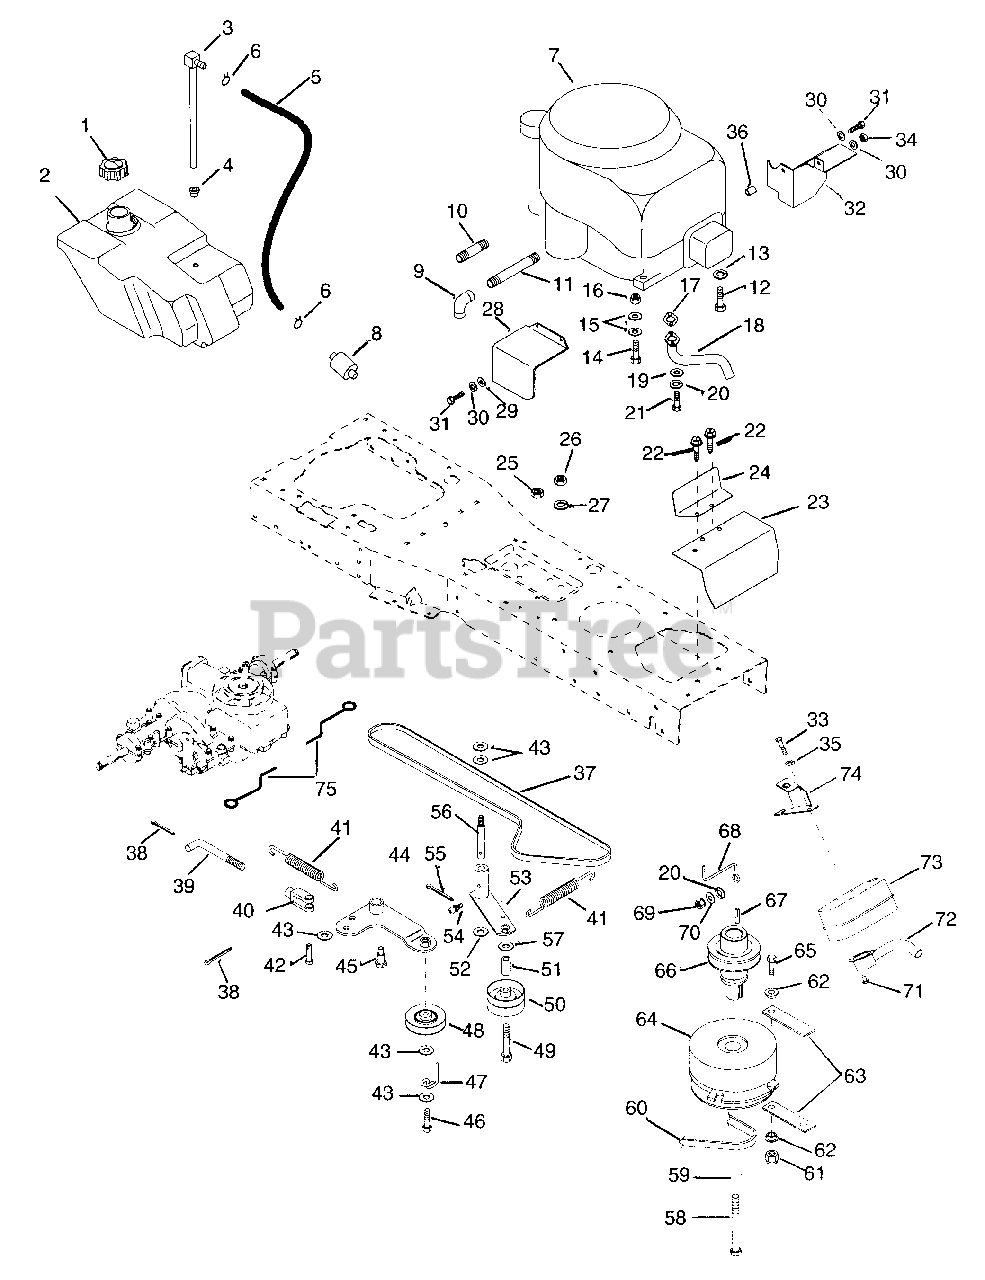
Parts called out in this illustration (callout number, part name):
1	FUEL CAP
2	FUEL TANK
3	TANK FITTING
4	BSHG-FLG .375 X 1.062 X .625 R
5	HOSE- FUEL LINE 34.00"
6	CLAMP-HOSE WIR.490/.510X.092#8
7	ENGINE- 12.0 OHV TEC
7	ENGINE- 14.0 OHV B&S I/C QUIET
7	ENGINE- 13.0 OHV TEC
7	ENGINE 15HP TEC OHV15-
8	FUEL FILTER
9	ELBOW .375-18 NPTF
10	NIPPLE
11	NIPPLE
12	SCR-TAP .375-16X1.25 HWH PL TR
13	WSHR-LK-EXT .375X.050
14	BLT-HEX .31-18X1.50 PL GR5
15	WSHR-FL-STL .328X.875X.062 PL
16	NUT-LK-TOP .312-18 GR C PL
17	GASKET- 12.5/13 TEC (#35-414)
17	GASKET:15-16.5HP TEC (#35-438)
18	EXHAUST TUBE WELDT- 12.5/13HP
18	EXHAUST TUBE WELDT- 15/16.5HP
19	WSHR-FL-STL .323X.625X.062 PL
20	WSHR-LK .313X.078 PL MED
21	BLT-HEX .31-18X.75 PL GR5
22	SCR-TAP .312-18X.75 HWH PL TR
23	HEAT SHIELD
24	SHIELD
25	NUT-LK-CTR .375-16 GR A PL
26	NUT-HEX .375-16
27	WSHR-LK .375X.094 MED PL
28	HEAT SHIELD- 14HP B&S
29	WSHR-FL-STL.312X.734X.065PL
30	WSHR-LK .250X.077 HVY PL
31	BLT-HEX .25-20X.75 PL GR2
32	HEAT SHIELD
33	BLT-HEX .25-20X.50 PL GR2
34	NUT-HEX .250-28 YWZC
35	WSHR-LK .250X.077 HVY PL
36	SPACER BUSHING .5 X .32 X .21
37	V-BELT, HA-WRAPPED
37	V-BELT, 4L-RAW EDGE
38	PIN-COTR .09X.75 PL
40	YOKE, .312-24 X 2.25
41	SG-TENS .091X.56X5.07 WLD 30
42	PIN-CLEV .312X.822 HDND PL
43	WSHR-FL-STL .390X.750X.125 PL
44	IDLER PIVOT ARM
45	BLT-SHLDR .38-16X1.25
46	BLT-HEX .38-16X1.75 PL GR2
47	BELT FINGER
48	IDLER-V 3X.38
49	BLT-HEX .38-16X3.00 PL GR2
50	IDLER-FLAT 2.75X.38 PAINTED
51	TUBE
52	WSHR-FL-STL .520X.827X.062 YZ
53	IDLER PIVOT ARM
54	FTG-LUBE .25-28X.256 YWZC
55	PIN-COTR .18X1.25 PL
56	SHOULDER STUD
57	WSHR-FL-STL.406X.812X.065PL
58	SCR-CAP .44-20X4.00 GR5 HHPL
59	WSHR-LK .438X.133 HVY
60	V-BELT, 4L-RAW EDGE
61	NUT-LK 10-24 NY PL
62	SPECIAL WASHER
64	ELECTRIC CLUTCH/BRAKE(1.8AMP)
65	BLT-HEX 10-24X1.00 PL GR2
66	SHEAVE EXTENSION SHAFT
67	KEY-SQ .25 X 1.25 X .25 SAE
68	BELT FINGER
69	NUT-JAM .312-18 PL
70	WSHR-FL-STL.312X.734X.065PL
71	SCR-TAP 8-32X.38 SL HWH PL 23
72	TAIL PIPE WELDT
73	MUFFLER ASSY
74	BRACKET
75	BELT FINGER
